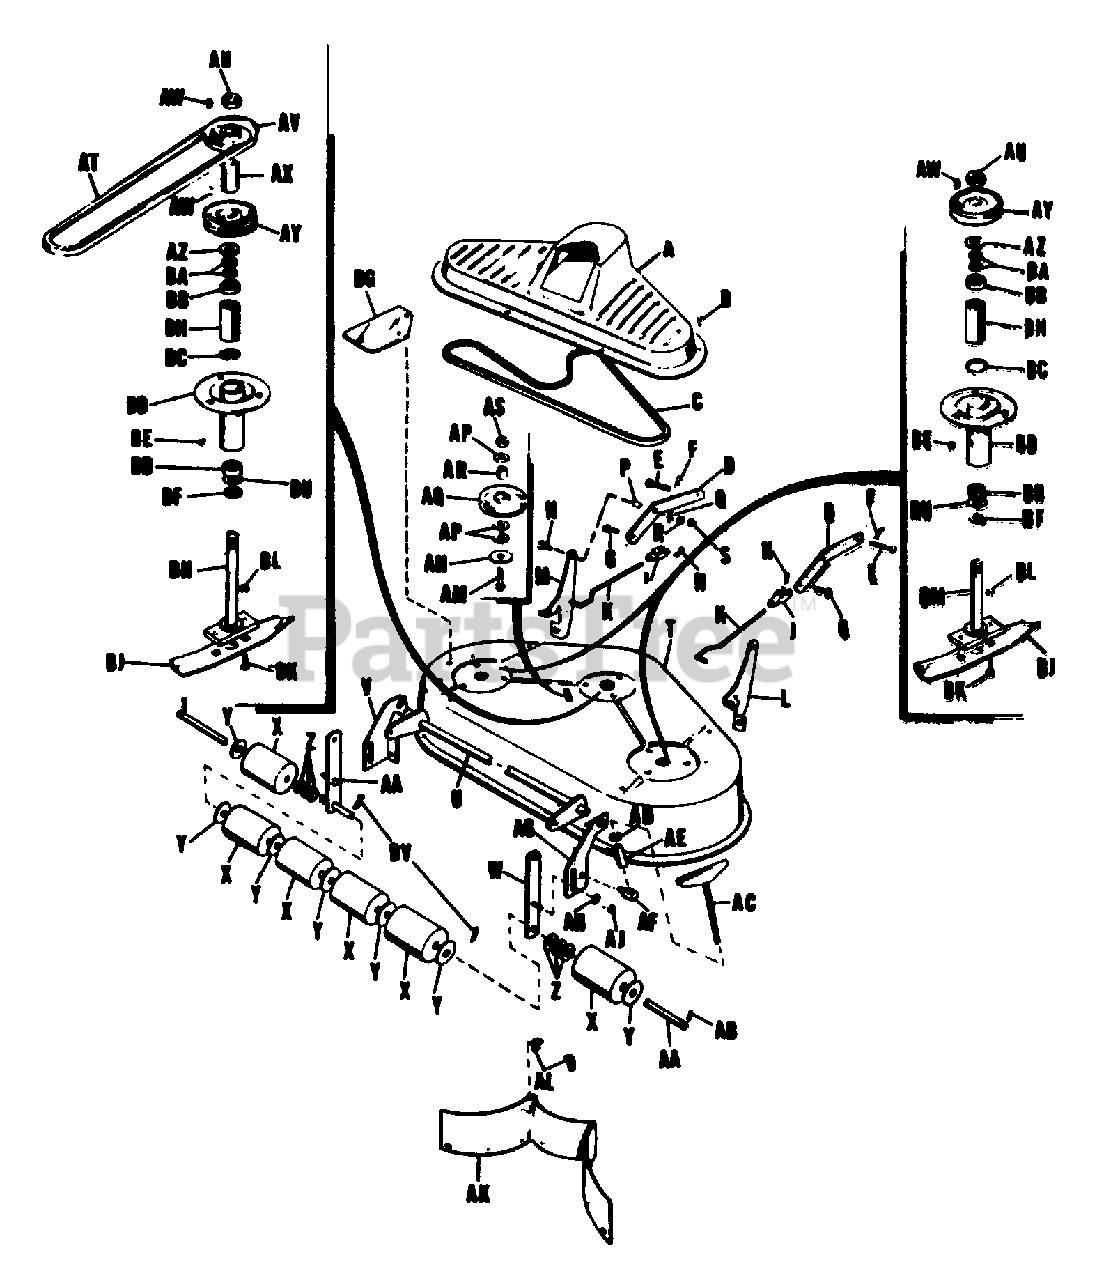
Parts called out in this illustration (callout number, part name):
A	Cover, Housing
B	Screw, Self-Tapping, Hex Hd., 1/4-20 x 3/8
C	V-Belt, Mower Spindle Drive
D	Lever, Front
F	Clip, Spring
G	Pin, Clevis
H	Pin, Cotter-3/32 x 3/4
J	Clevis, Adj.
K	Rod, Height Adj.
L	Bracket, Front, R.H.
M	Bracket, Front, L.H.
N	Capscrew, Hex Hd., 3/8-16 x 1
Q	Washer, Plain, 3/8
R	Washer, Lock, 3/8
S	Nut, Full Hex, 3/8-16
U	Lever, Assy., Rear
V	Bracket, Roller, L.H.
W	Bar Assy., Roller
AA	Bar & Shaft Assy.
AB	Pin, Cotter
AC	Screw, Assy. Adj.
AD	Washer, Plain
AE	Socket, Assy. Crank
AG	Bracket, Roller, R.H.
AH	Washer, Plain, 5/16
AJ	Nut, Hex, Full Lock, 3/8
AL	Clip Baffle
AM	Bolt Carriage, 3/8-16 x 1
AP	Washer, Plain, 5/16
AQ	Pulley Idler
AS	Nut, Hex, Full Lock, 3/8-16
AT	V-Belt, Cross Drive
AU	Nut Hex Jam, Center Lock 3/4-16
AV	Pulley, Cross Drive
AW	Woodruff Key, 3/16 x 5/8, #61
BC	Ring, Backing
BD	Tube Assy., Arbor
BG	Deflector
BH	Arbor Assy., Drive
BM	Arbor Assy.
BV	Cotter Pin
